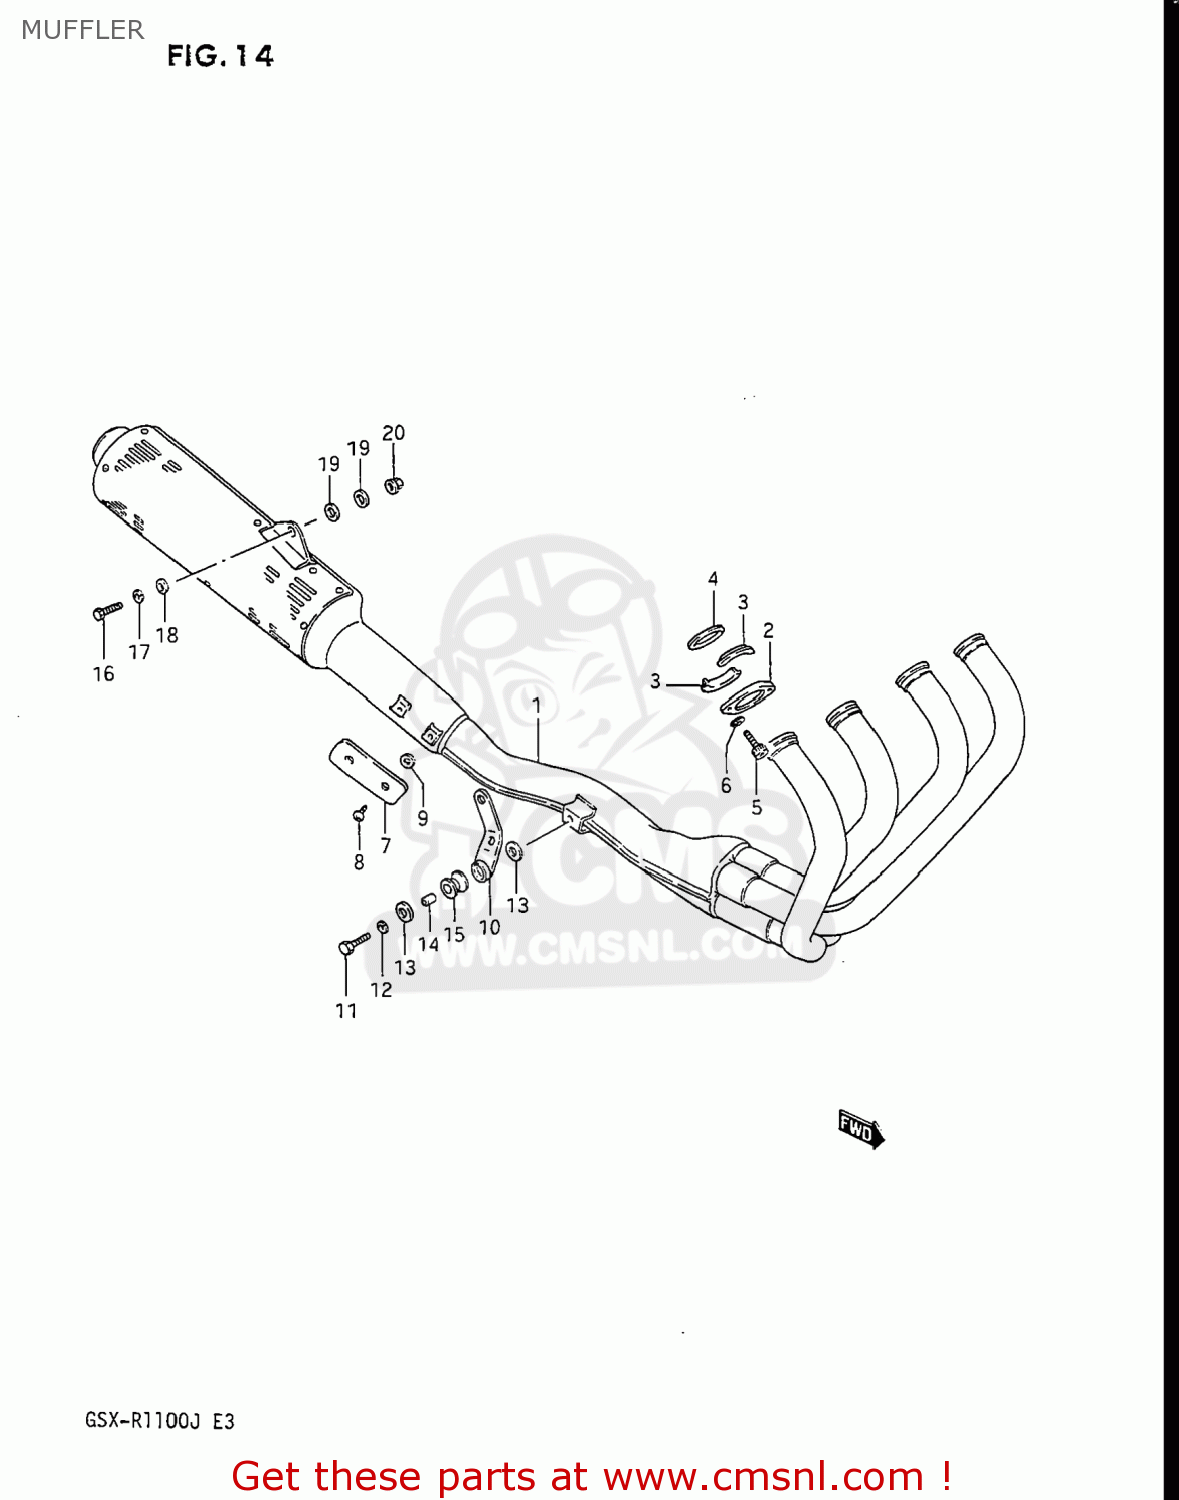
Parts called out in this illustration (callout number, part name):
1	MUFFLER ASSEMBLY
2	CLAMP,EXHAUST PIPE
3	PLATE,EXHAUST PIPE
4	GASKET,EXHAUST PIPE (NAS)
5	BOLT
6	WASHER
7	COVER,MUFFLER,FRONT
8	SCREW
9	GASKET (NAS)
10	DAMPER,MUFFLER SUPPORT
11	BOLT 8X35
12	WASHER
13	WASHER (8.5X20X1.6)
14	SPACER (8.6X12X17.5)
15	CUSHION
16	BOLT
17	WASHER,LOCK
18	WASHER 10MM
19	WASHER
20	NUT
